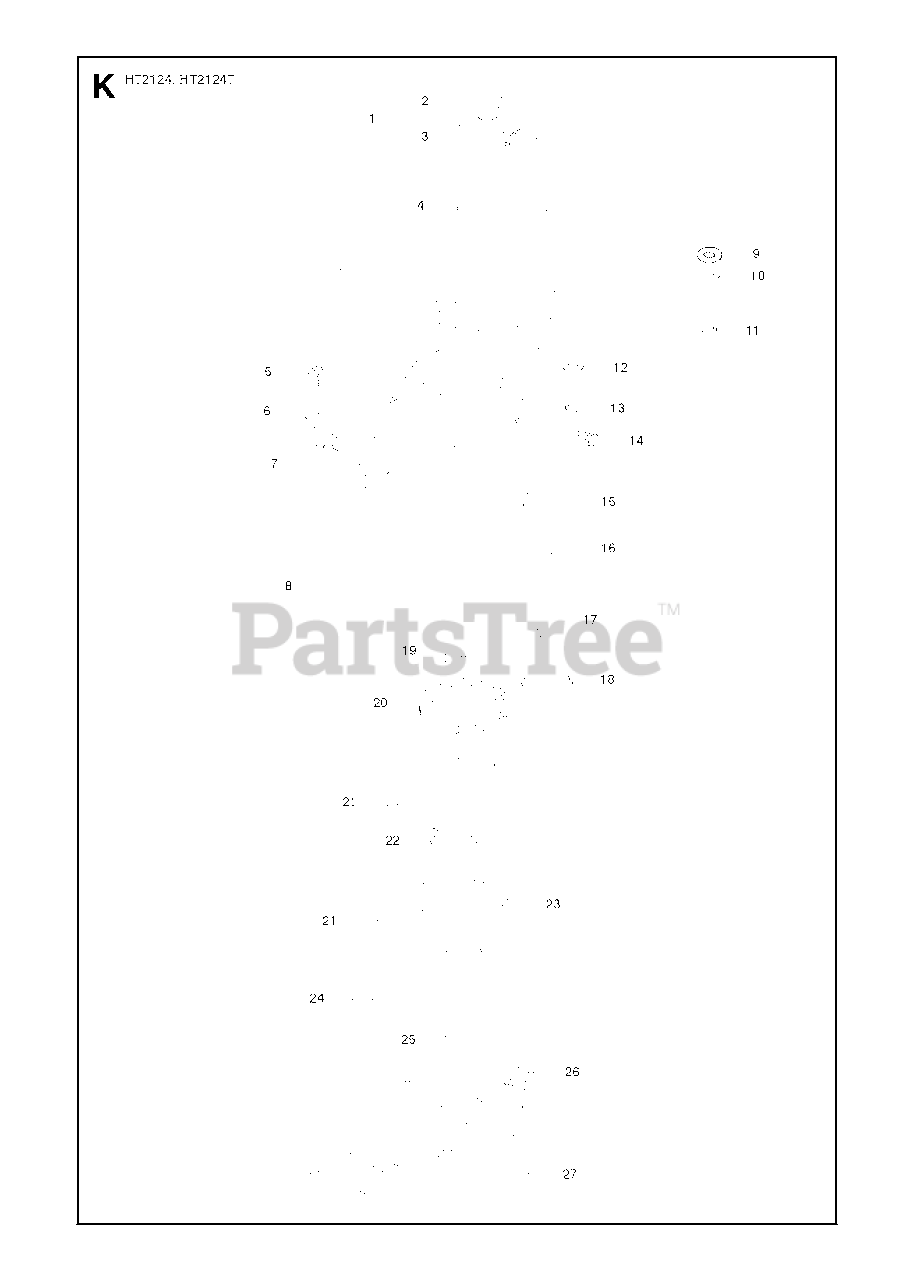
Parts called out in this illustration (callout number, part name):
2	SPRING
3	CLUTCH
4	CLUTCH DRUM
7	GEAR HOUSING
8	GREASE FILTER
9	WASHER - M6
11	BOLT FLANGE
14	GREASE FITTING
18	RETAINING RING
20	CRANK GEAR
22	RETAINING RING
